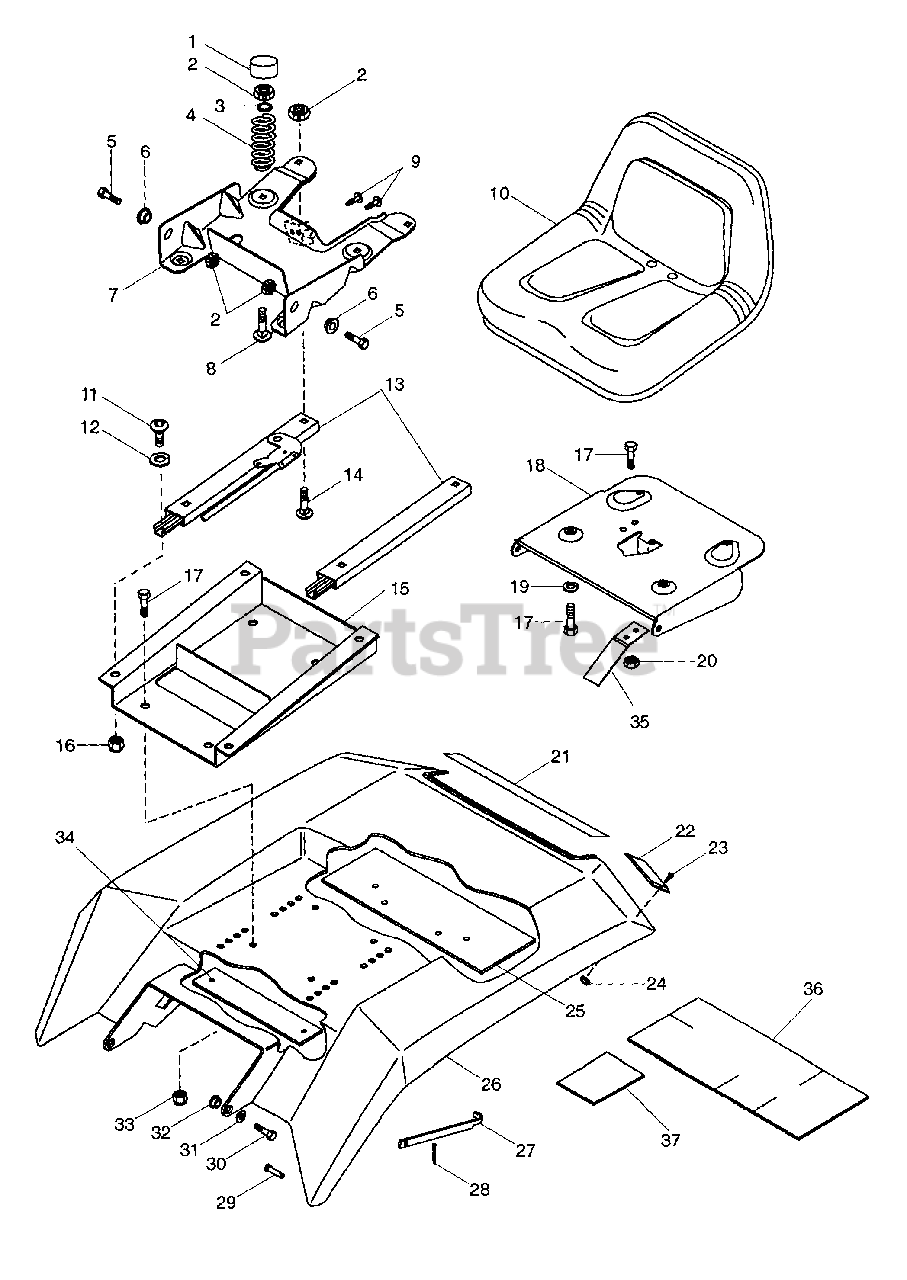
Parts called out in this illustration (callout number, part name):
1	Tube Cap
2	Nut-Locking .312-18
3	Washer-Flat-Steel .344 x .688 x .065
4	Spring-Compression .148 x 1.23 x 2.41
5	Bolt-Hex .31-18 x .75 Grade 5
6	Bushing-Flange .325 x .465 x .333 x .685
7	Seat Box
8	Bolt-Round Head Square Neck .31-18 x .75 Grade 5
9	Screw-Tapping 12-24 x .50
10	Seat V-560
11	Screw-Cap Button Head .31-18 x .50 Grade 5
12	Washer-Lock External .313 x .030
13	Seat Slides
14	Bolt-Round Head Square Neck .31-18 x .62
15	Seat Box
16	Nut-Hex .312-18 Grade 2
17	Bolt-Hex .31-18 x .75 Grade 2
18	Seat Pivot Plate
19	Washer-Lock .312 x .097
20	Nut-Flange .312-18
21	Decal, Gravely Logo
22	Reflector, Rectangular Reflex
23	Screw-Machine 10-32 x .50
24	Nut-Locking 10-32
25	Bracket, Seat Support
26	Weldment, Seat Pan Head Notched
27	Strap, Fender Hold Up
28	Pin-Cotter .062 x .75
29	Pin-Clevis .250 x .406
30	Bolt-Hex .38-16 x 1.00 Grade 5
31	Washer-Flat-Steel .406 x .812 x .065
32	Bushing-Flange .406 x .88 x .270 x .140
33	Nut-Locking-Center .312-18 Grade 2
34	Plate, Control Shaft
35	Spring Plate
36	Heat Shield
37	Heat Shield
